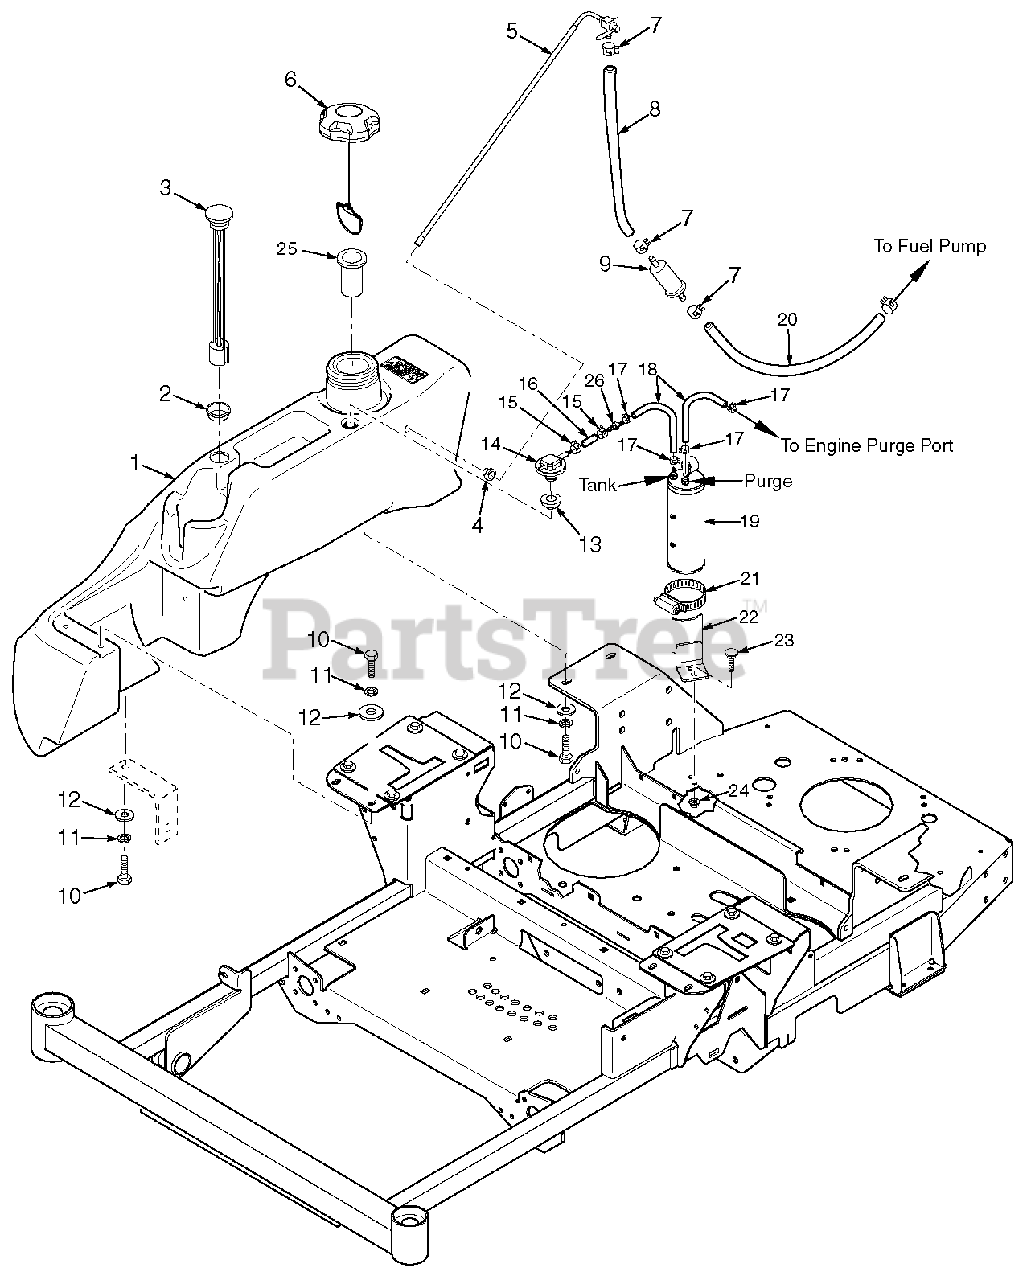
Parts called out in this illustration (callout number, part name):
1	Fuel Tank Assembly - SPZ
2	Grommet, Fuel Gauge
3	Fuel Gauge Assembly
4	Bushing, .56 Dia. Viton
5	Fuel Tube Assembly
6	Fuel Cap, Tethered
7	Clamp, Fuel Hose 1/4"
8	Fuel Hose, 1/4" Non-Perm (order by inch)
9	Fuel Filter
10	Bolt, Hex Head 5/16-18 x 3/4"
11	Lockwasher, 5/16" Spring
12	Flatwasher, 5/16-.375 x .875 x .083
13	Grommet, Viton
14	Remote Vent
15	Clamp, Fuel Hose 7/32"
16	Hose, 1/4" Vapor Recovery (order by inch)
17	Clamp, Vapor Recovery Hose
18	Hose, 3/16" (order by inch)
19	Carbon Canister
20	Fuel Hose
21	Clamp, Hose
22	Bracket Weldment, SFZ
23	Bolt, Carriage 5/16-18 x 3/4"
24	Nut, Serrated Flange 5/16-18
25	Tube, Fuel Tank Insert
26	Mender, 1/4 x 3/16 w/0.02 Hole
